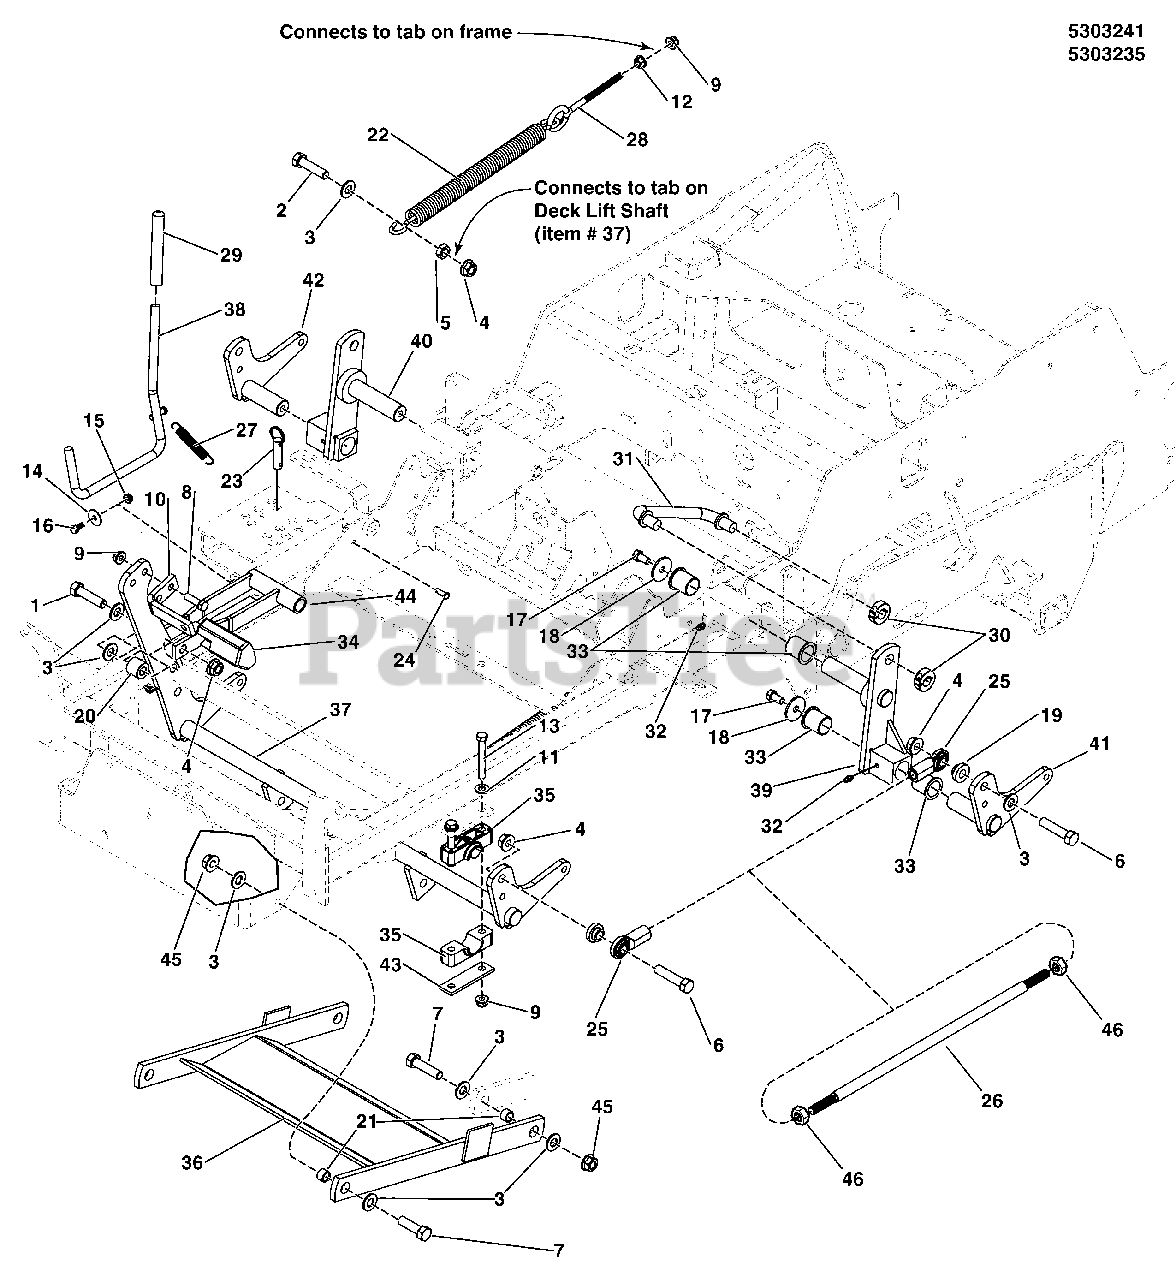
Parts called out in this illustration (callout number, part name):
1	BOLT, 1/2-13 X 2-3/4 GD5 YZ
2	BOLT, 1/2-13 X 2 GD5 YZ
3	WASHER, 1/2 SAE
4	NUT, 1/2-13 HEX NYLOCK FLANGE
5	NUT, 1/2-13 HEX JAM
6	BOLT, 1/2-13 X 2-1/4 GD5 YZ
7	BOLT, 1/2-20 X 1-3/4 GD8 YZ
8	BOLT, 3/8-16 X 1-1/4 GD5
9	NUT, 3/8-16 HEX NYLOCK FLANGE
10	PEDAL, FOOT - BLK
11	WASHER, 3/8 SAE
12	NUT, 3/8-16 HEX SERRATED FLANGE
13	BOLT, 3/8-16 X 2-3/4 GD5 YZ
14	WASHER, 1/4 FENDER
15	NUT, 1/4-20 HEX NYLOCK FLANGE (5025391)
16	BOLT,1/4-20X5/8
17	BOLT, 3/8-16 X 3/4, GD5, YZ WITH PATCH
18	WASHER, .390 X 1.50 X .109, YZ
19	SPACER, .52 X 1.00 X .44. CZ
20	SPACER, .52 X 1.00 X .88, CZ
21	INSERT, BEARING
22	SPRING-EXT, 1.00 ODX13.25LGX.177WR, BLK
23	PIN, HITCH, 1/2 X 2.00 OAL, YP
24	CLEVIS PIN, 1/4 X 1/2, CZ
25	JOINT-BALL .500-20 THD .500ID, CLR ZINC
26	ROD, DECK LIFT, 19.25
27	SPRING-EXT, .740 ODX2.025LGX.072WR, BLK
28	EYE BOLT, 3/8-16 X 6, 3.0 THREAD
28	EYE BOLT, 3/8-16 X 4, 2.13THRD, 1EYE, CZ
29	GRIP, FOAM, .475 X 4.35 X .095
30	COLLAR, 5/8 SPLIT
31	ROD, SUSPENSION LINK, IS700
32	GREASE FITTING, 1/4-28 STRAIGHT
33	BUSHING, 1.00 X 1.13 X 1.38, PLASTIC
34	RUBBER, FOOT PEDAL
35	PIVOT BLOCK, PLASTIC
36	WELD, PULLER BAR, IS700Z - BLK
37	WELD, DECK LIFT SHAFT, IS700 - ORG
37	WELD, DECK LIFT SHAFT, CIT XT - ORG
38	WELD, ROD DECK LIFT, IS700 - BLK
39	WELD, REAR LIFT - LH - BLK
40	WELD, REAR LIFT - RH - BLK
41	WELD, DECK LIFT LEVER, LH - BLK
42	WELD, DECK LIFT LEVER, RH - BLK
43	PLATE, PIVOT BLOCK SUPPORT - BLK
44	WELD, DECK HEIGHT LINK, IS700 - RED
45	NUT, 1/2-20 HEX NYLON LOCK
46	NUT, 1/2-20 HEX JAM
